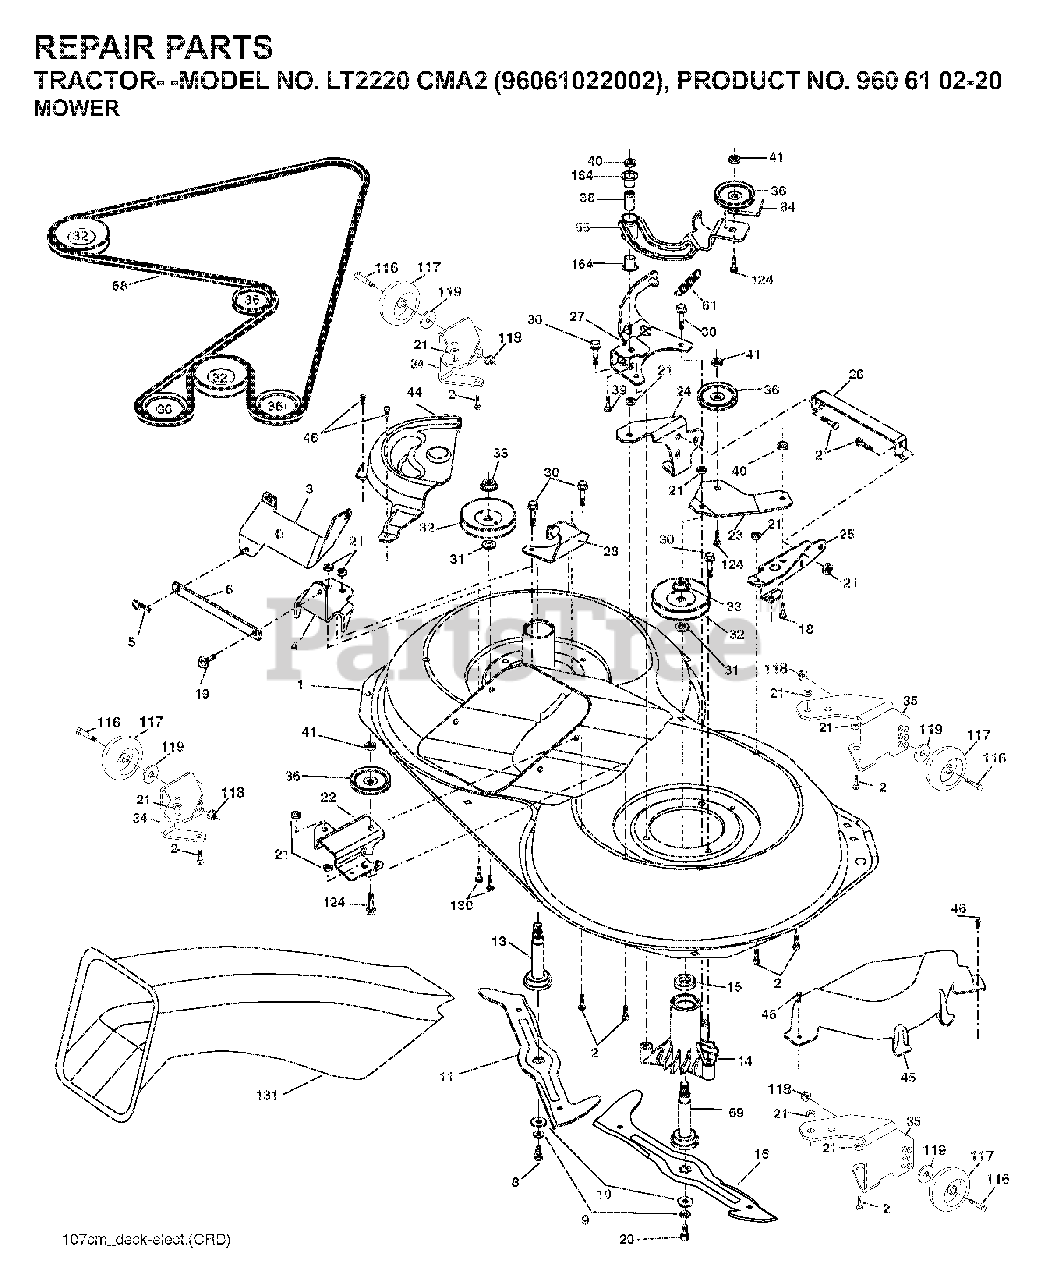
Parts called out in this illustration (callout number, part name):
2	BOLT
3	BRACKET
5	RETAINER-SPRNG RB
6	BAR SWAY
9	LOCKWASHER
10	WASHER.BLADE
11	BLADE.3N1.LH.CRD
13	SHAFT ASM VENT
14	HSG MANDREL
16	BLADE.3N1.RH.CRD
19	BOLT SHD 5/16-18
21	LOCKNUT
22	BRACKET
23	BRACKET
27	BRACKET
30	SCREW, WASHER HEAD
31	WASHER.SPACER.MANDREL
33	NUT.FLANGE.LOCK.TOP
36	PULLEY.IDLER.4.25
40	LOCKNUT
41	NUT LOCK FLG 3/8-16 UNC
45	MANDREL COVER
46	SCREW.1/4-20X5/8
68	HEX-BELT 107 MOWER
69	SHAFT.ASM.W/LWR.BRG.RH.THREAD
84	KEEPER, BELT IDLER
116	BOLT.SHOULDER.3/8-16X3-5/8
117	WHEEL. GUAGE RALLY
118	NUT LOCK FLG 3/8-16 UNC
124	BOLT.3/8-16X1.50
131	CHUTE BAGGER
164	BRNG T
